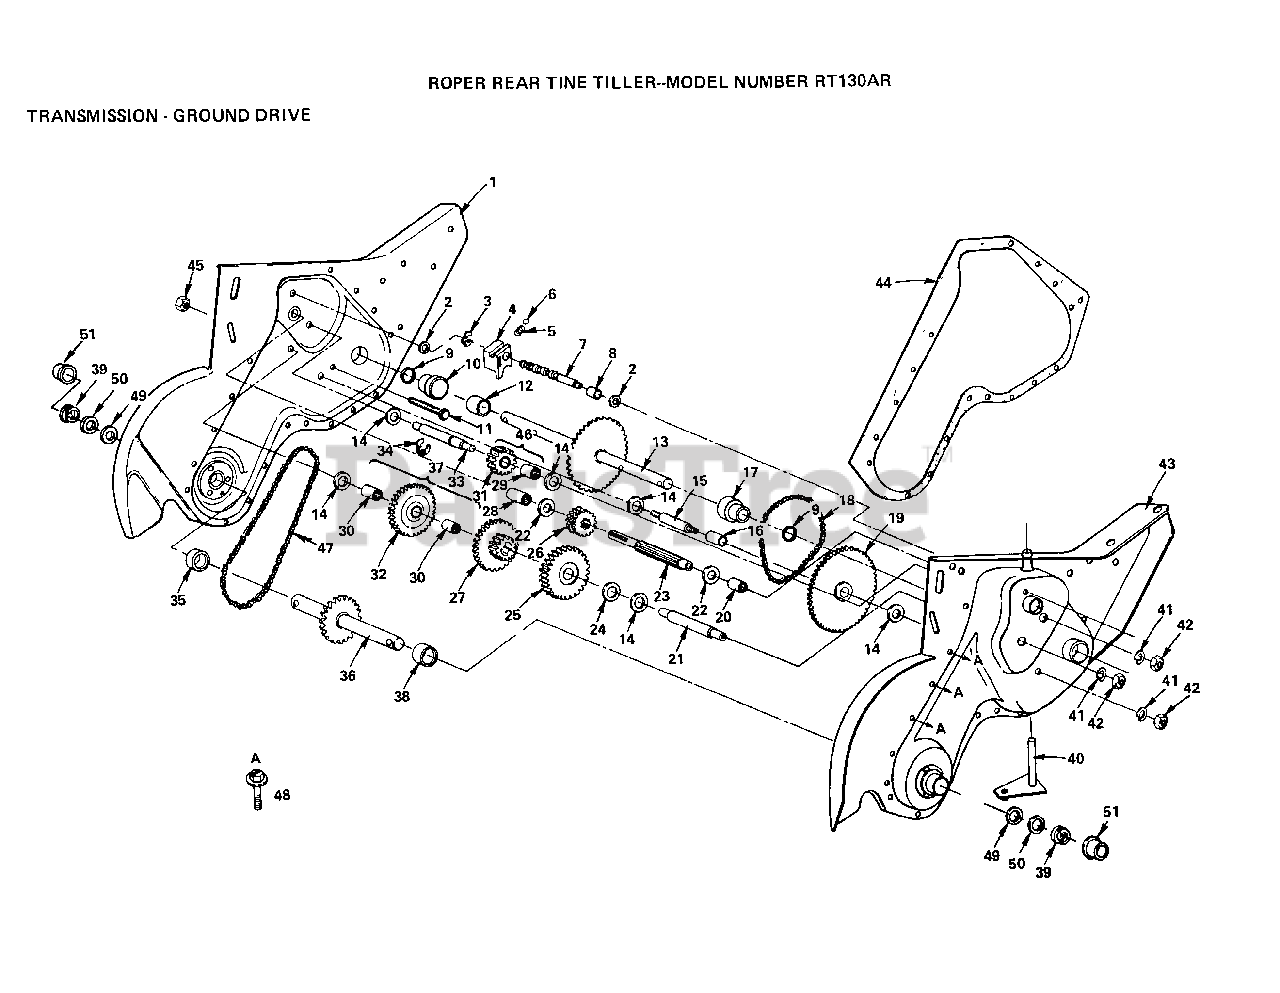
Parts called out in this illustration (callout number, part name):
1	GEARCASE ASSY
2	WASHER SEAL CRT
3	KLIP RING
4	SHIFT FORK TI
5	SPRING-SHIFT CRT
7	SHAFT SHIFT CRT
8	SPACER SPLIT CRT
9	O RING CRT
10	"CRT, BEARING"
11	SCRW WHIZ LOK CRT
14	WASHER
15	SHFT 2ND RED. CRT
18	CHAIN CRT
19	SPRCKT 8 GEAR CRT
20	"TI, BEARING"
21	REDUCTION SHFT TI
22	"T, BEARING"
23	SHAFT-INPUT CRT
24	BRNG RACE
26	PINION-INPUT CRT
27	CLUSTER GEAR TI
28	NEEDLE BRNG LT
29	NEEDLE BEARING TI
30	BEARING
31	GEAR-REV IDLR CRT
32	SPROCKET ASSY
33	SHAFT CRT
34	KLIP RING
39	RING SPIRAL CRT
40	ARM ASSY CRT
41	LOCKWASHER
42	NUT.ASF.HEX.7/16
45	NUT.HEX.5/16-18
46	GEAR ASSY CRT
48	SCREW CRT
51	CUP.FORMED.
